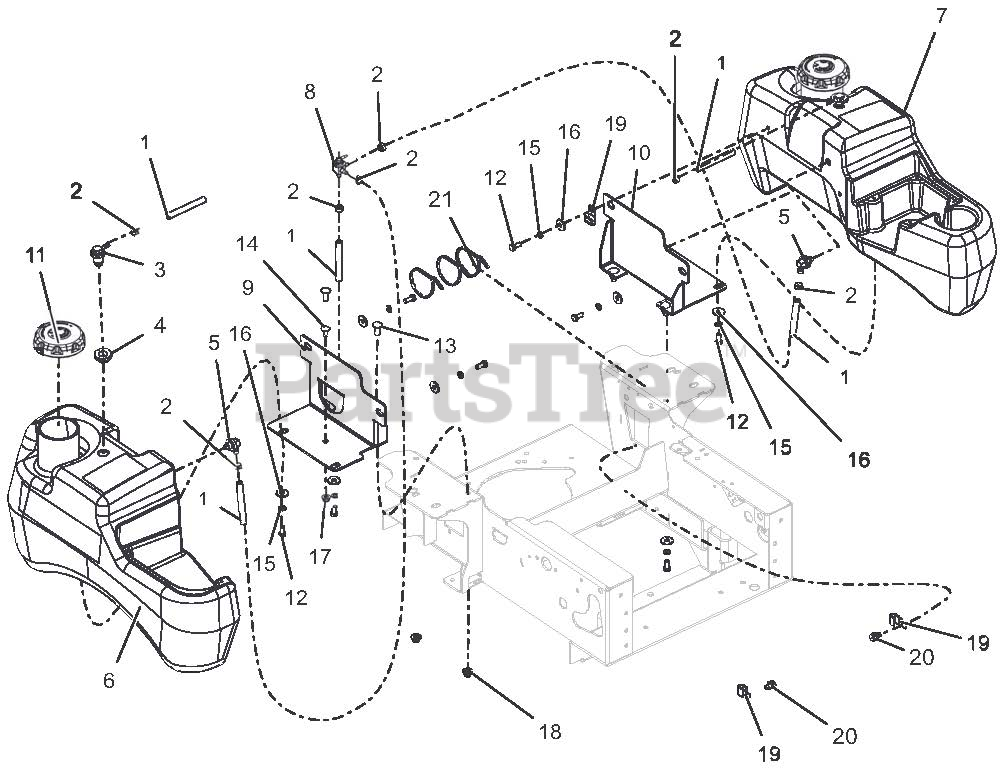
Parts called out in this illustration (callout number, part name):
1	.25 LOW-PERM GAS HOSE
2	CLAMP, FUEL LINE
3	VALVE, COMBINATION
4	GROMMET, REMOTE VENT NITRILE
5	ASS'Y, SMALL/ MED TANK FUEL PICK-UP
6	TANK, GAS - RH MEDIUM GRAVELY
7	TANK, GAS - LH MEDIUM GRAVELY
8	VALVE, FUEL
9	BRKT, RH MEDIUM FUEL TANK MTG
10	BRKT, RH MEDIUM FUEL TANK MTG
11	CAP, NON NONVENT AUTOLOCK
12	BLT-HEX .31-18X.75 GR5 YWZC
13	BLT-RDHDSHSQNK.38-16X1.0 G5YZ
14	BLT-RDHDSQNK .31-18X.75 G5 YWZC
15	WSHR-LK .31X.078 REG YWZC
16	WSHR-FL-STL .328X1.00X.094 YWZC
17	NUT-LK-NYL-FLG .31-18 YWZC
18	NUT-LK-NYL-FLG .38-16 YWZC
19	CLAMP, J
20	SCR-TAP .38-16X.50 HWH TR YWZ
21	CABLE, TIE 5.50 LG
